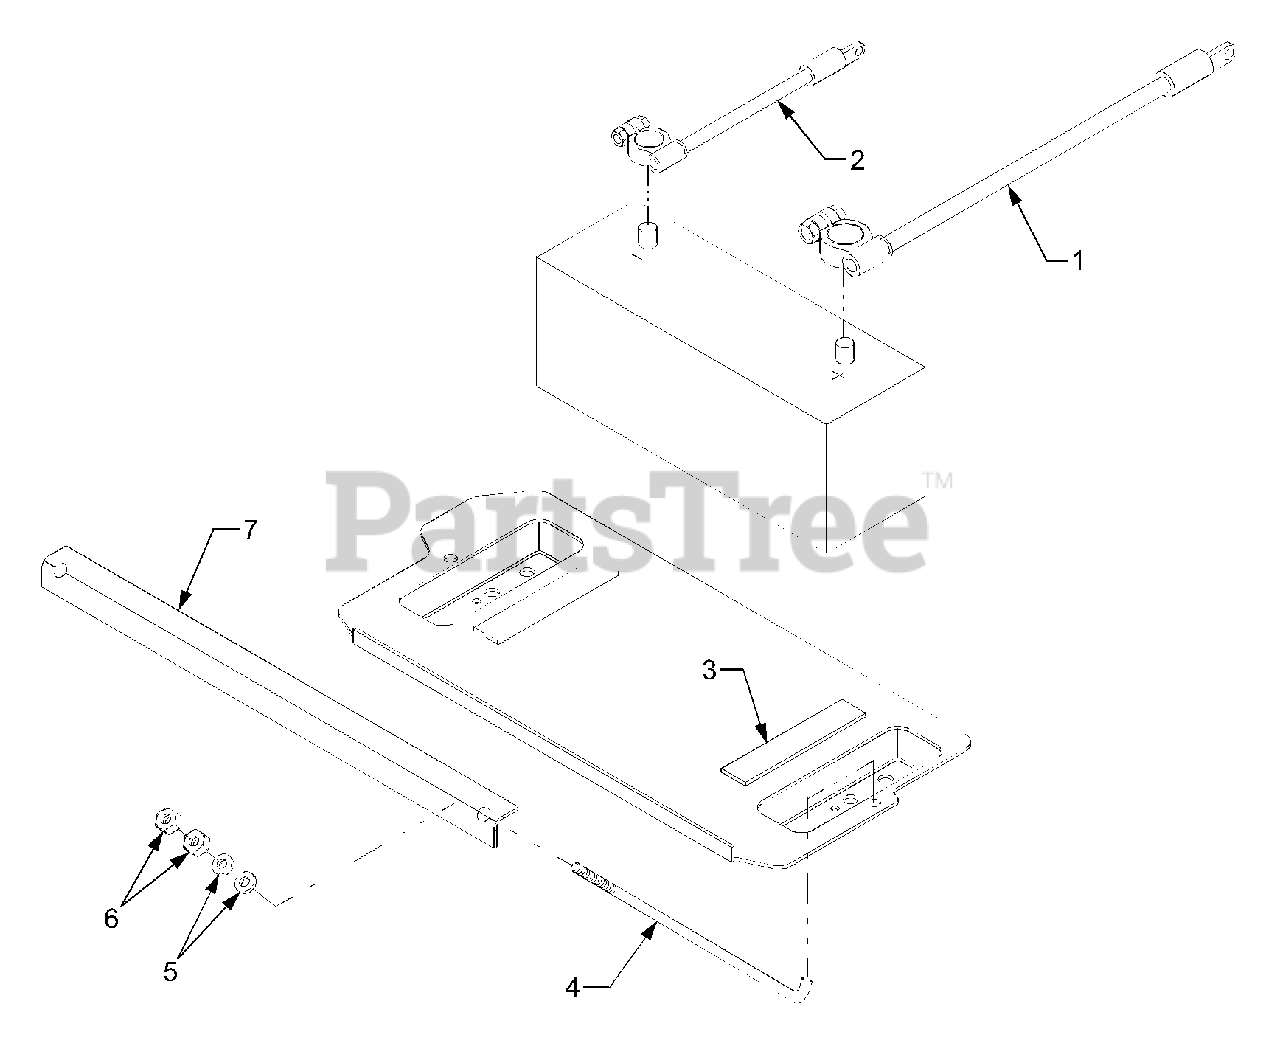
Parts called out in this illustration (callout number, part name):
1	Cable, Battery Positive
2	Cable, Battery Ground
3	Rubber, Battery
4	Bolt, Battery Hook
5	Washer, Plain
7	Plate, Battery Lock
